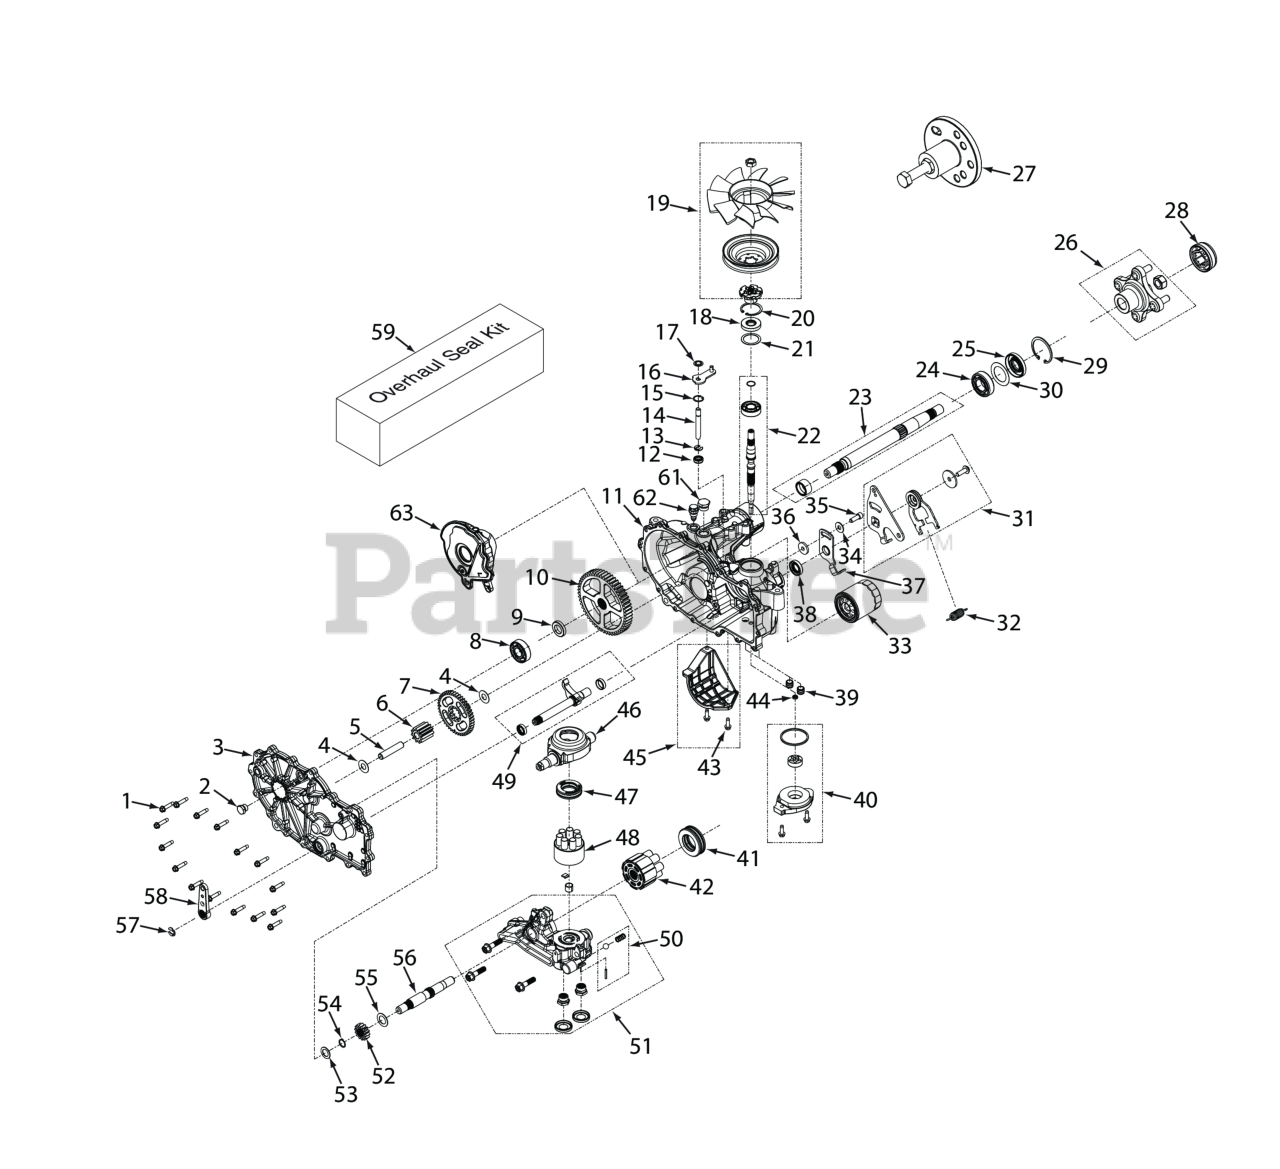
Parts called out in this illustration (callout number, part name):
1	Bolt, Hex Head 1/4-20 x 1-1/8"
2	Plug, External Hex Vent 9/16-18
3	Kit, Side Cover LH
4	Washer, .5 x 1.0 x .03
5	Jackshaft Pin
6	Gear, 11T
7	Gear, 45T
8	Kit, Bearing
9	Spacer, .750 x 1.320 x .257
10	Gear, 54T
11	Kit, Main Housing LH, Charge, Control
12	Seal, Lip, .375 x .75 x .25
13	Ring, .Retaining .375 External
14	Rod, By-Pass
15	R i n g , Retaining .750 Internal
16	Arm, Bypass (LH)
17	Ring, Retainging .375 External
18	Seal, Lip 17 x 40 x 7
19	Kit, Fan/Pulley
20	R i n g , Retaining 2.06 Internal
21	Washer, 1.23 x 1.56 x .04
22	Kit, Input Shaft
23	Kit, Shaft, Axle
24	Bearing, Ball 1.0 x 52 x 15 Open
25	Seal, Lip TC4 1.0 x 2.06 x .38
26	Hub, 4-Bolt
27	Kit, Hub Puller
28	Cap, Axle
29	R i n g , Retaining 2.06 Internal
30	Spacer, 1.355 x 2.035 x .021
31	Kit, RTN Bi-Directional (Right Side)
32	Spring, Extension, RTN - 44lbs
33	Filter, Oil
34	Washer, 7/16 x 7/8 OD x .06 HT
35	Bolt, Hex Head Cap Screw 5/16-24 x 1" Patch
36	Spacer, .32 ID x 1.005 OD x .1495 Thk
37	Arm, Neutral (Left Side)
38	Seal, Lip 18 x 32 x 7
39	Tube, Charge Triple O-ring
40	Kit, Charge Pump
41	Thrust Ball Bearing Assembly
42	Kit, 16cc Cylinder Block Assembly (steam
43	Bolt, 1/4-20 x 3/4"
44	Kit, Gerotor Seal
45	Kit, Filter Guard (LH)
46	Trunnion, Swashplate
47	Ball Thrust Bearing
48	Kit, Cylinder Block
49	Kit, Inboard, RH Rot B / LH Rot A (LH)
50	Kit, Charge Relief
51	Kit, Charge Relief
52	Washer, Flat, .71 x 1.16 x .04
53	Washer, HT .62 ID x 1.0 OD x .05 Thick
54	Ring, Retaining .625
55	Washer, .72 x 1.16 x .04
56	Shaft, Motor
57	Ring, Retaining External .375"
58	Handle, Brake
59	Kit, Seal (ZT-2800)
61	Plug, 3/4-16
62	Fitting 9 /16 - 18, Breather
63	Expansion Tank, Internal LH
